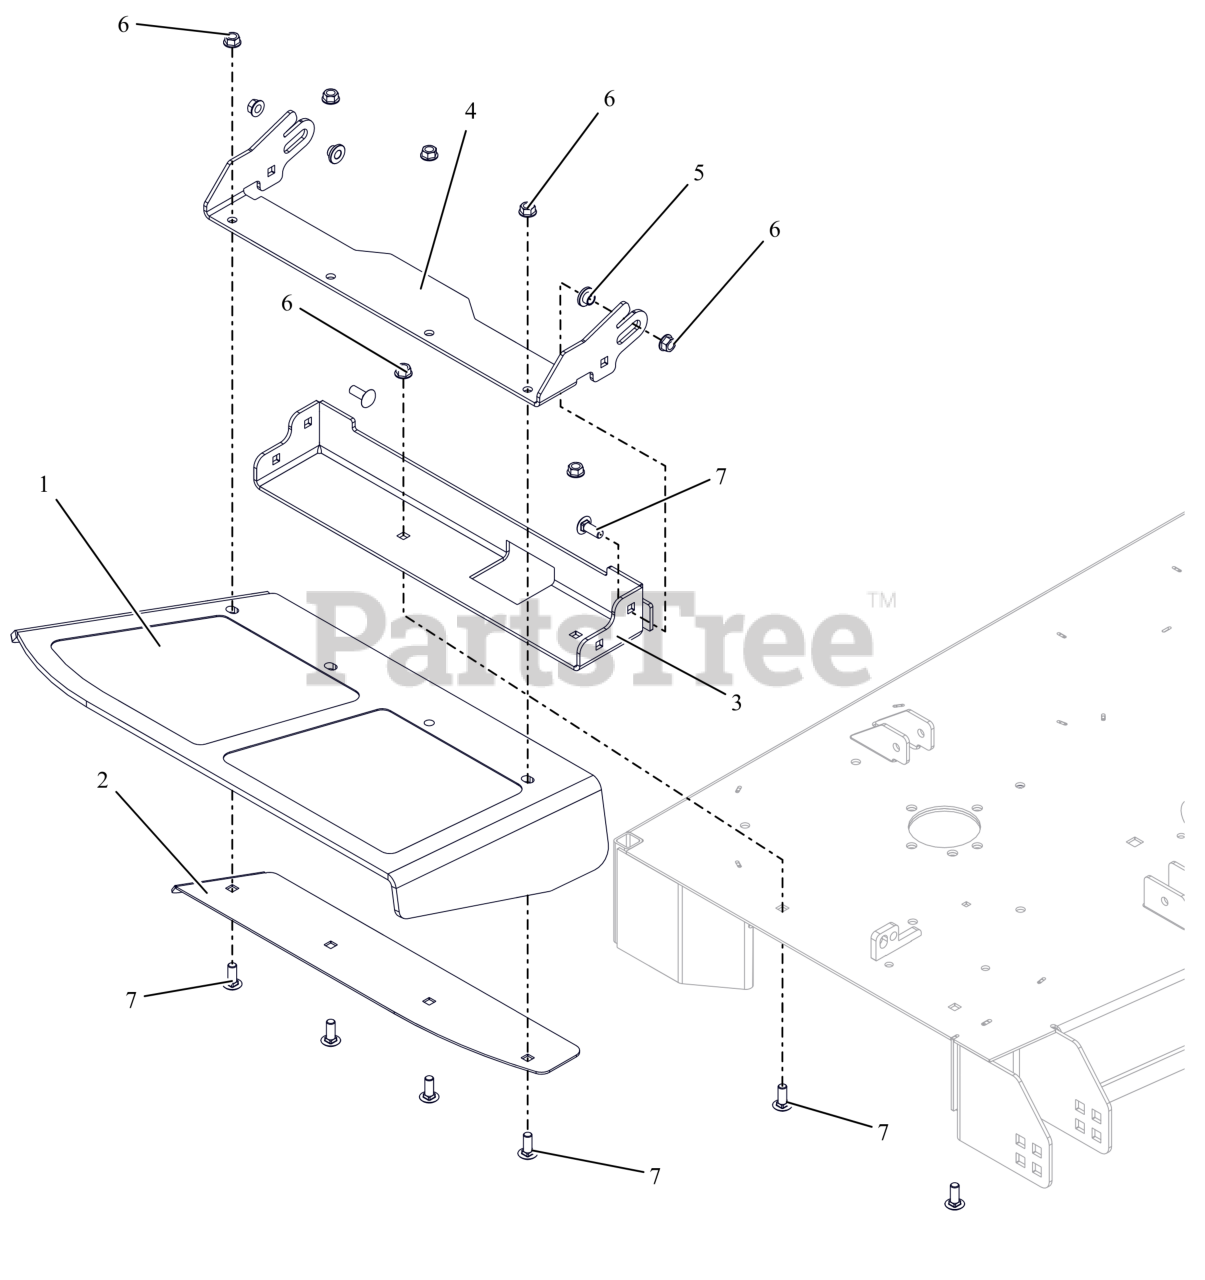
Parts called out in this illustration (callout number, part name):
1	CHUTE, FORMED RUBBER DISCHARGE
2	PLATE- DISCH CHUTE CLAMP
3	KIT-DISCH CHUTE LG ORG W/DECAL
4	BRKT- CHUTE MTG
5	BSHG-FLG .385X.500X.875X.406
6	NUT-LK-CTR-FLG .375-16 GF ZCC
7	BLT,RHSSN .38-16X1.00 G5 ZCC
